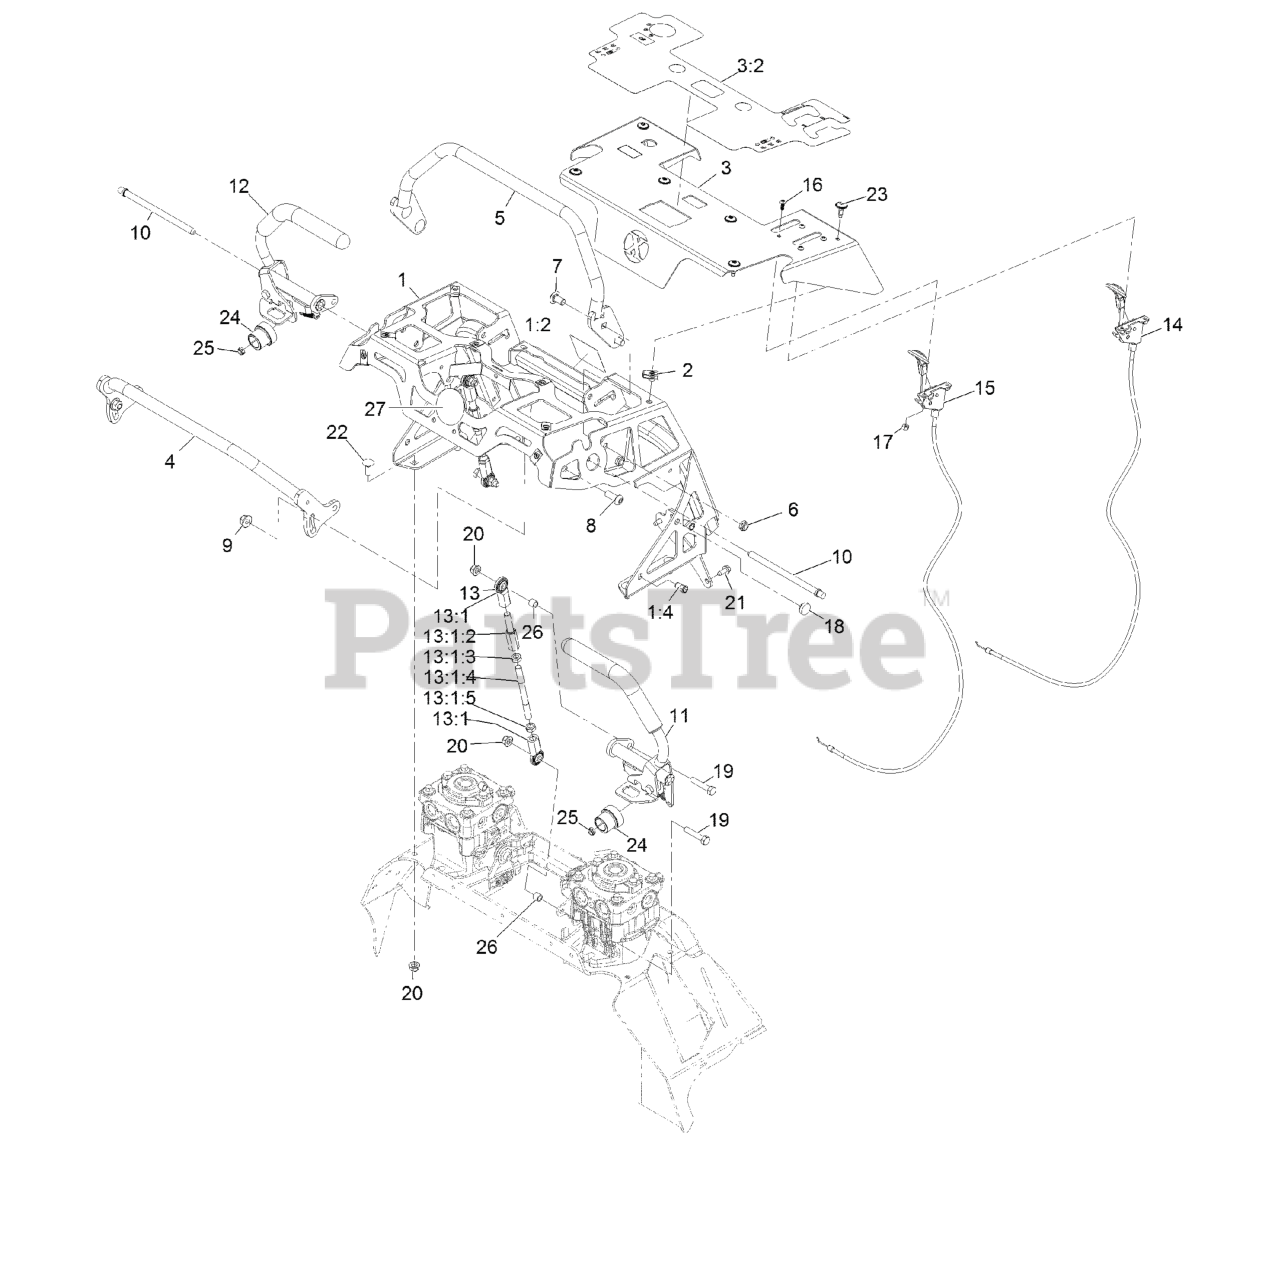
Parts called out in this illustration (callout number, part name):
1	ASM-CTRL TOWER
1:2	DECAL-HYD FLUID WARN
1:4	NUT-CLINCH,HEX
3	ASM, CONTROL PANEL W/ DECALS
3:2	DECAL-CONTROL PANEL NON-EFI
4	WELD, FRONT REF BAR
5	WELD, REAR REF BAR
7	SCREW-CARR
8	SCREW-HSBH
9	NUT-HF, NI
10	PIN, PIVOT
11	ASM, MOTION CONTROL, LT
12	ASM, MOTION CONTROL, RT
13	ASM, LINKAGE
13:1	ASM, Motion Control Link
13:1:2	ROD-ADJUSTMENT
13:1:3	NUT-HEX JAM, LH
13:1:5	NUT-HJ
14	CONTROL, CHOKE
15	CONTROL, THROTTLE
16	SCREW, BHCS
17	NUT-LOCK, NI
19	SCREW-HH
20	NUT-HF, NI
21	SCREW-HWH
22	SCREW-CARR
23	SCREW, TORX
25	NUT-LOCK, NI
27	DECAL-COVER
